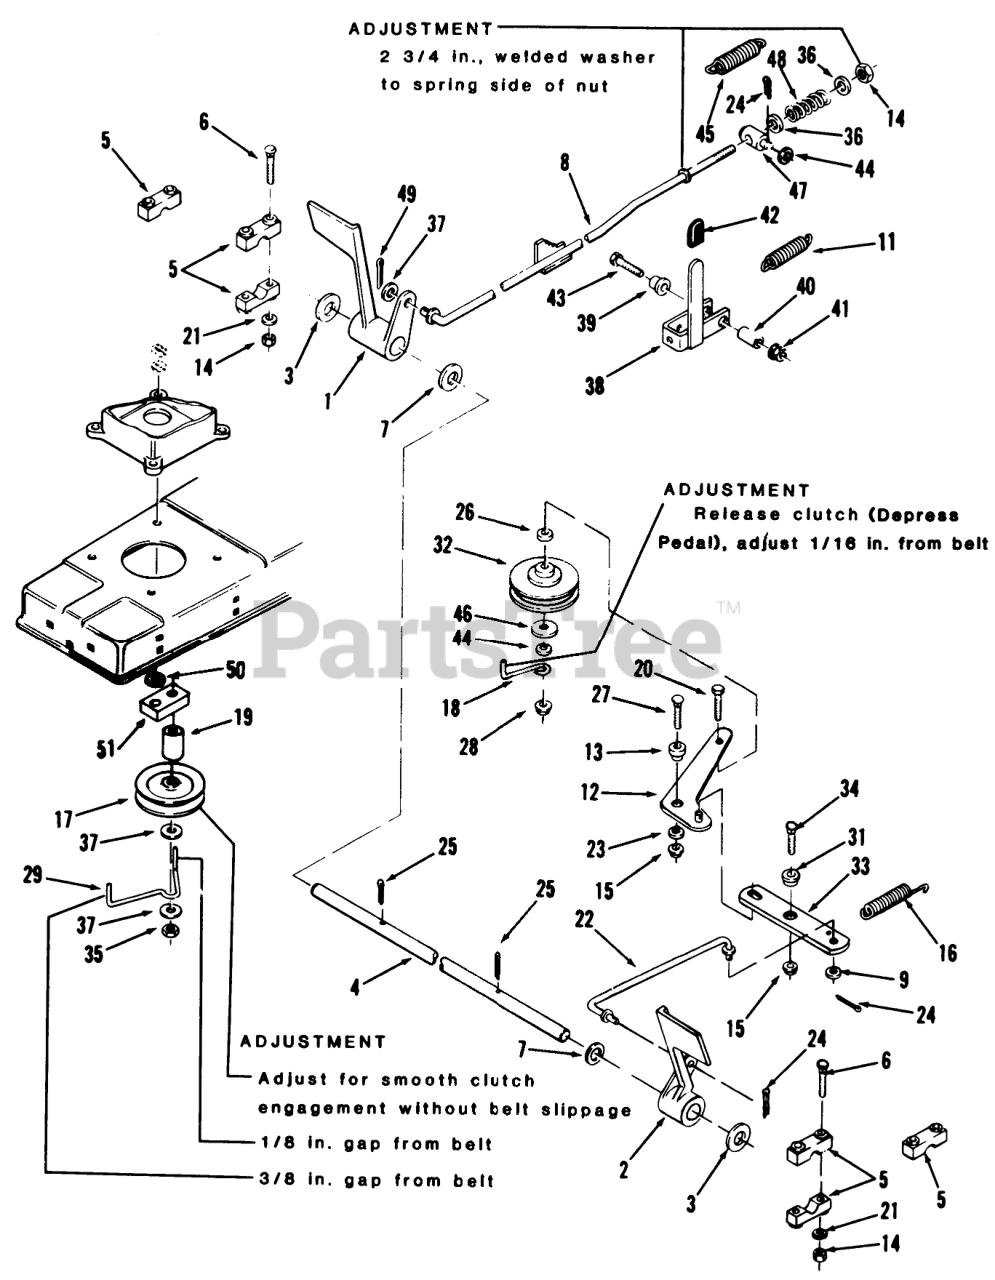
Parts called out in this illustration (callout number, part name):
1	PEDAL-BRAKE *R
2	PEDAL CLUTCH *R
3	Special Washer
6	BOLT-CAR
9	WASHER-PLAIN
11	SPRING-EXTENSION
13	SPACER-IDLER ARM
14	NUT-LOCK, NI
16	SPRING-CLUTCH
17	PULLEY-IDLER STATION
20	WASHER-FLAT
21	WASHER-PLAIN
22	Rod-Clutch
24	PIN-COTTER
25	PIN-COTTER
27	SCREW-CARR
32	IDLER PULLEY
34	BOLT-CARR
35	NUT-LOCK, NI
36	WASHER-FLAT
37	WASHER-FLAT
39	SPACER
40	SPACER
42	GRIP
43	SCREW-HH
44	WASHER-FLAT
45	SPRING-EXTENSION
46	WASHER
47	TRUNNION-LIFT
50	WASHER-LOCK, INTERNAL
